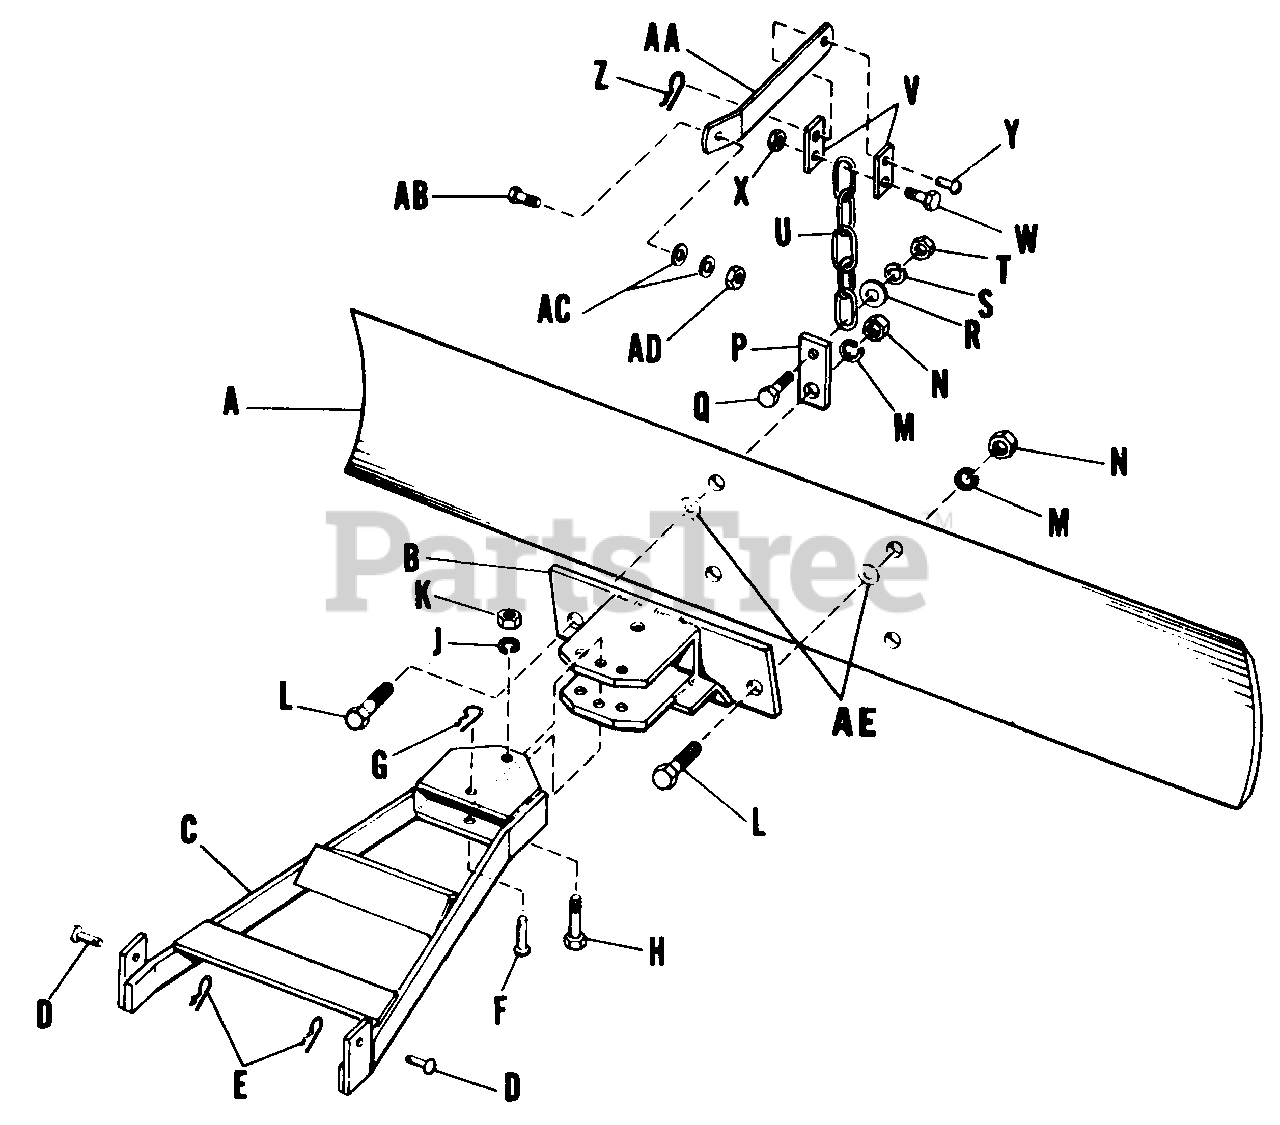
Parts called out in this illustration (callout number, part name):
A	Blade, Grader. 42"
B	Hitch Assembly
C	Draw Bar Assembly
D	Pin
E	Spring Clip
G	Spring Clip
H	Capscrew, Hex Head, 5/8"-11 NC x 3" lg.
J	Lockwasher, 5/8"
K	Nut, Hex, Full, 5/8"-11 NC
L	Capscrew, Hex Head, 5/8"-11 NC x 2" lg.
M	Lockwasher, 5/8"
N	Nut, Hex, Full, 5/8"-11 NC
Q	Capscrew, Hex Head, 3/8"-16 NC x 1 1/4" lg.
R	Plain Washer, 3/8"
S	Lock Washer, 3/8"
T	Nut, Hex, Full, 3/8"-16 NC
U	Chain
W	Capscrew, Hex Head, 3/8"-16 NCx 1 1/4" lg.
X	Nut, Hex, Full, Lock, 3/8"-16 NC
Z	Spring Clip
AB	Capscrew, Hex Head, 3/8"-16 NCx 1 1/4" lg.
AC	Plain Washer, 3/8"
AD	Nut, Hex, Full, Lock, 3/8"-16 NC
AE	Flat Washer, 1-1/16"
